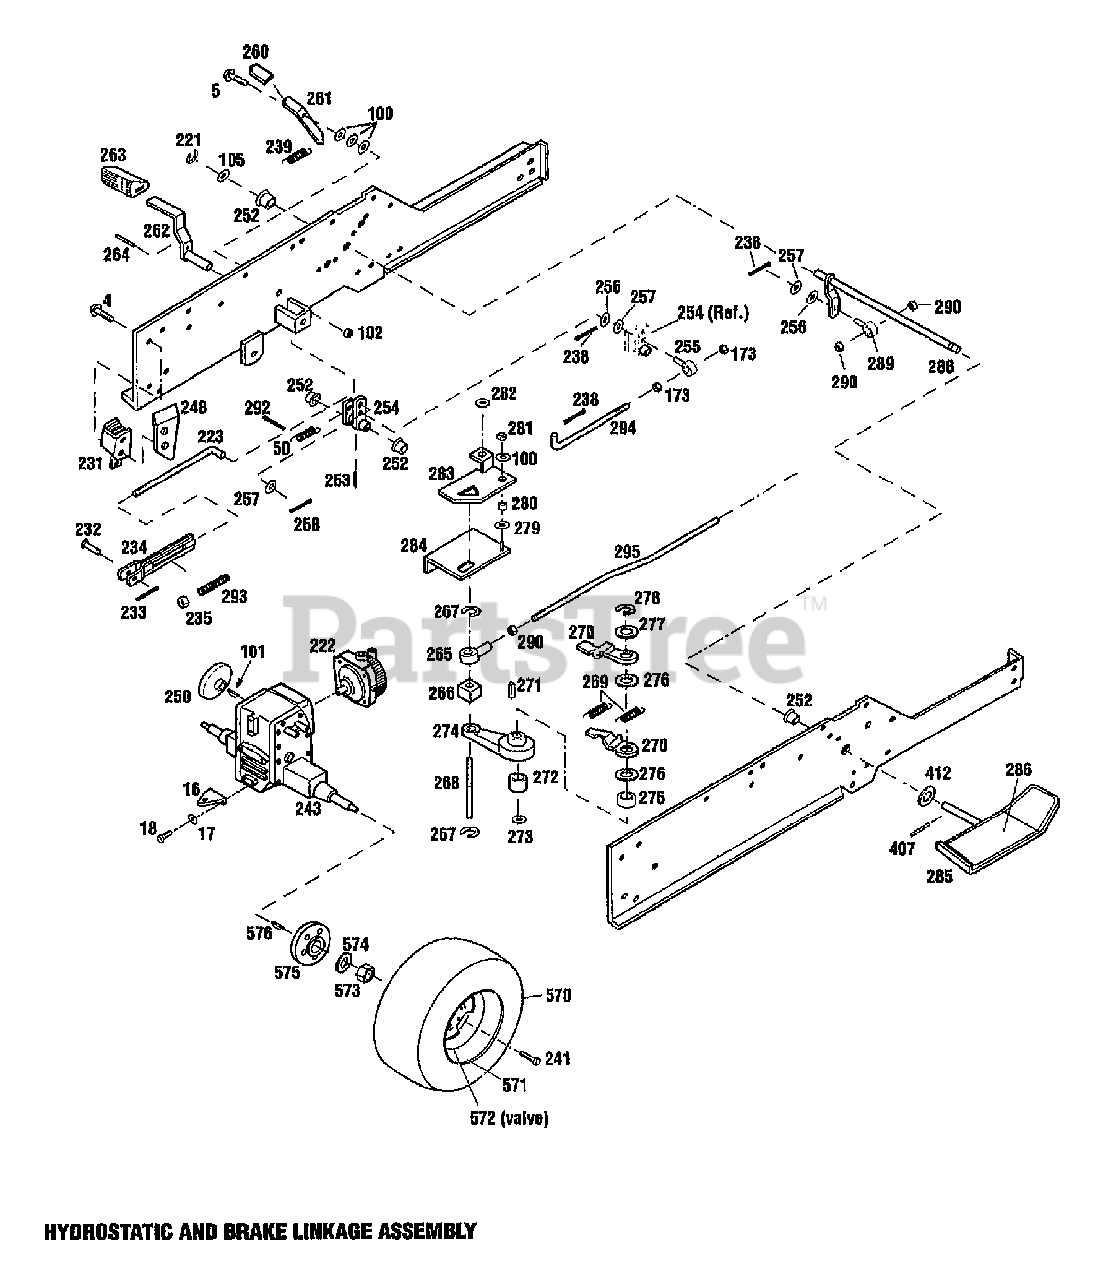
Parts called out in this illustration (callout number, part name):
5	SCR-HFLK 3/8-16X1.00 ZP
16	HITCH-DRAWBAR
17	WASHER-LK .5
18	SCR-HH 1/2-13X1.25 G5 ZP
100	WASHER-FLAT 3/8 SAE
101	KEY-WOODRUFF .25X.75
102	NUT-LOCK 3/8-16
105	WASHER-1.115X.637X.06
173	NUT-HEX 5/16-18 ZP
221	RING-RETAIN .625 ID
222	PUMP-HYDRO
223	ROD-BRAKE
231	ASSY BRAKE-CYLINDER
232	PIN-CLEVIS .25X.62
233	PIN-COTTER
234	SPRING-YOKE ASSM
235	NUT-SPECIAL
238	PIN-COTTER .09X.75 ZP
239	SPRING
241	BOLT-HUB
243	ASSM-TRANSAXLE
248	BRKT-TRANS SUPPORT
250	BRAKE-DISC
252	BEARING-FLANGE
253	PIN-DRIVE .187X1.0
255	SWIVEL
256	WASHER-.632X.39X.0329
257	WASHER-FLAT 5/16 SAE
258	PIN-COTTER .125 X .75 ZP
262	PEDAL-BRAKE
263	FOOT REST
264	PIN-ROLL .188X.75
265	ROD-END
267	RING-RET.EXT .437 ID
268	PIN-CONTROL
269	SPRING
271	KEY-WOODRUFF 1/8 X 5/8
272	WASHER-1.06X.531X.1 ZP
273	NUT-H/LK 1/2-13
274	ARM-SPEED CONTROL
275	BEARING
276	WASHER-THRUST
277	WASHER
278	RING-RET
279	WASHER-1.75X.39X.059
280	SPACER-.625X.4X.2
281	NUT-HEX/JAM 3/8-16 ZP
282	WASHER-.75X.312X.065 ZP
283	PLATE-NEUTRAL
284	PLATE-NEUTRAL
285	ASSM-PEDAL HYDRO
286	PAD-FOOT PEDAL
288	SHAFT-SPEED CONTROL
289	SWIVEL
290	NUT-HEX/JAM 7/16-20
292	PIN-COTTER .120X1.00 ZP
293	SPRING-COMPRESSION
294	ROD-BRAKE CONTROL
295	ROD-SPEED CONTROL
407	PIN-ROLL .188X1.0
412	WASHER-1.0X.64X.09
571	RIM-WHEEL REAR
571	RIM-WHL
572	STEM-VALVE
573	NUT-H/LK 3/4-10
574	SPACER-1.812X.765X.179
575	HUB-WHEEL
576	KEY-WOODRUFF .312X1.12
